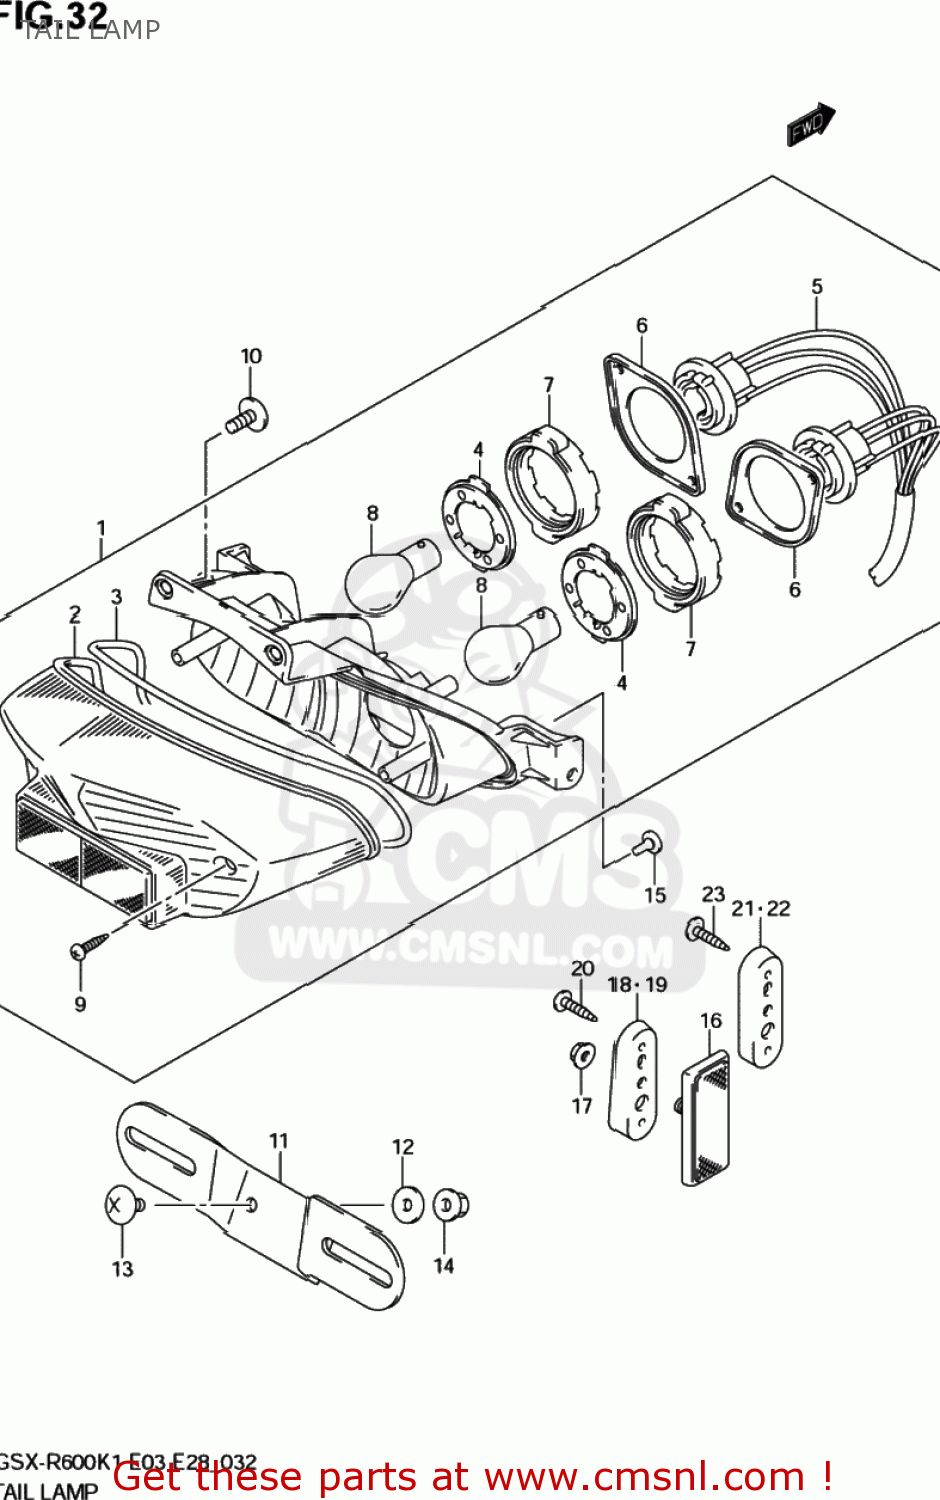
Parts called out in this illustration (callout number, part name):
1	LAMP ASSY,RR COMBINATION
2	LENS
3	GASKET (NAS)
4	PLATE NO.1
5	SOCKET & CORD
6	PLATE NO.2
7	CUSHION
8	BULB(12V21/5W)
9	SCREW
10	SCREW
11	BRACKET,LICENSE PLATE
12	WASHER(6.5X20X1.6)
13	SCREW
14	NUT
15	CUSHION
16	REFLECTOR ASSEMBLY,REAR
17	NUT
18	SPACER, RH
19	SPACER,RR SIDE RR,L
20	SCREW 6X12
21	SPACER,RR SIDE RR,R
22	SPACER,RR SIDE RR,L
23	SCREW
